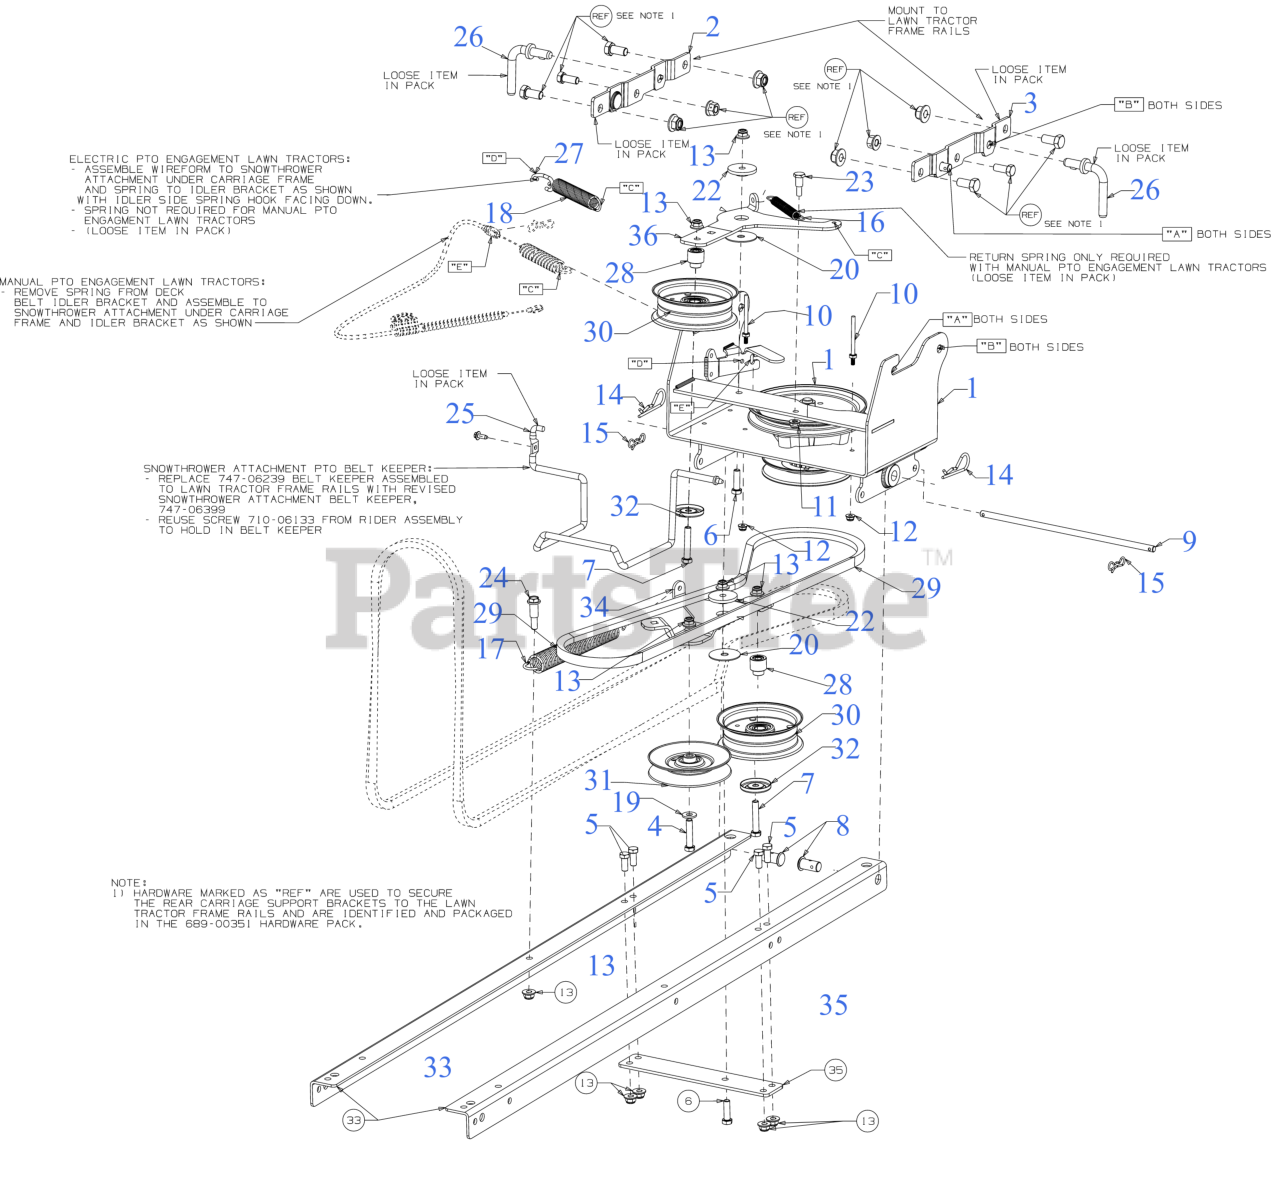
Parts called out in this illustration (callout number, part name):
1	SPINDLE & BRACKET ASSEMBLY
2	HANGER BRACKET (RH)
3	HANGER BRACKET (LH)
4	HEX SCREW 3/8-16 x 1.75 GR5
5	SCREW 3/8-16 x .880 GR5
6	SCREW 3/8-16 x 1.25 GR5
7	SCREW 3/8-16 x 2.0 GR 8
8	CLEVIS PIN .62
9	BELT KEEPER ROD
10	BELT KEEPER .25X2.64
11	FLANGE LOCK NUT 5/16-18
12	FLANGE LOCK NUT
14	INTERNAL COTTER PIN
15	BOW TIE COTTER PIN
16	EXTENSION SPRING
17	EXTENSION SPRING
18	SPRING KIT-IDLER
19	FLAT WASHER .385X.870X.090
20	THRUST WASHER
22	SHOULDER SPACER
23	SHOULDER SCREW
24	SHOULDER SCREW .50X.925
25	BELT KEEPER ROD
27	EXTENSION SPRING HOOK
28	SHOULDER SPACER
29	V-BELT B SEC x 68.45
30	IDLER PULLEY 4.50" DIA
31	IDLER PULLEY 5.06 DIA
32	IDLER PULLEY CAP
33	UNDER CARRIAGE RAIL(POWDER BLACK)
34	IDLER BRACKET PIVOT (POWDER BLACK)
35	IDLER SUPPORT BRACKET (POWDER BLACK)
